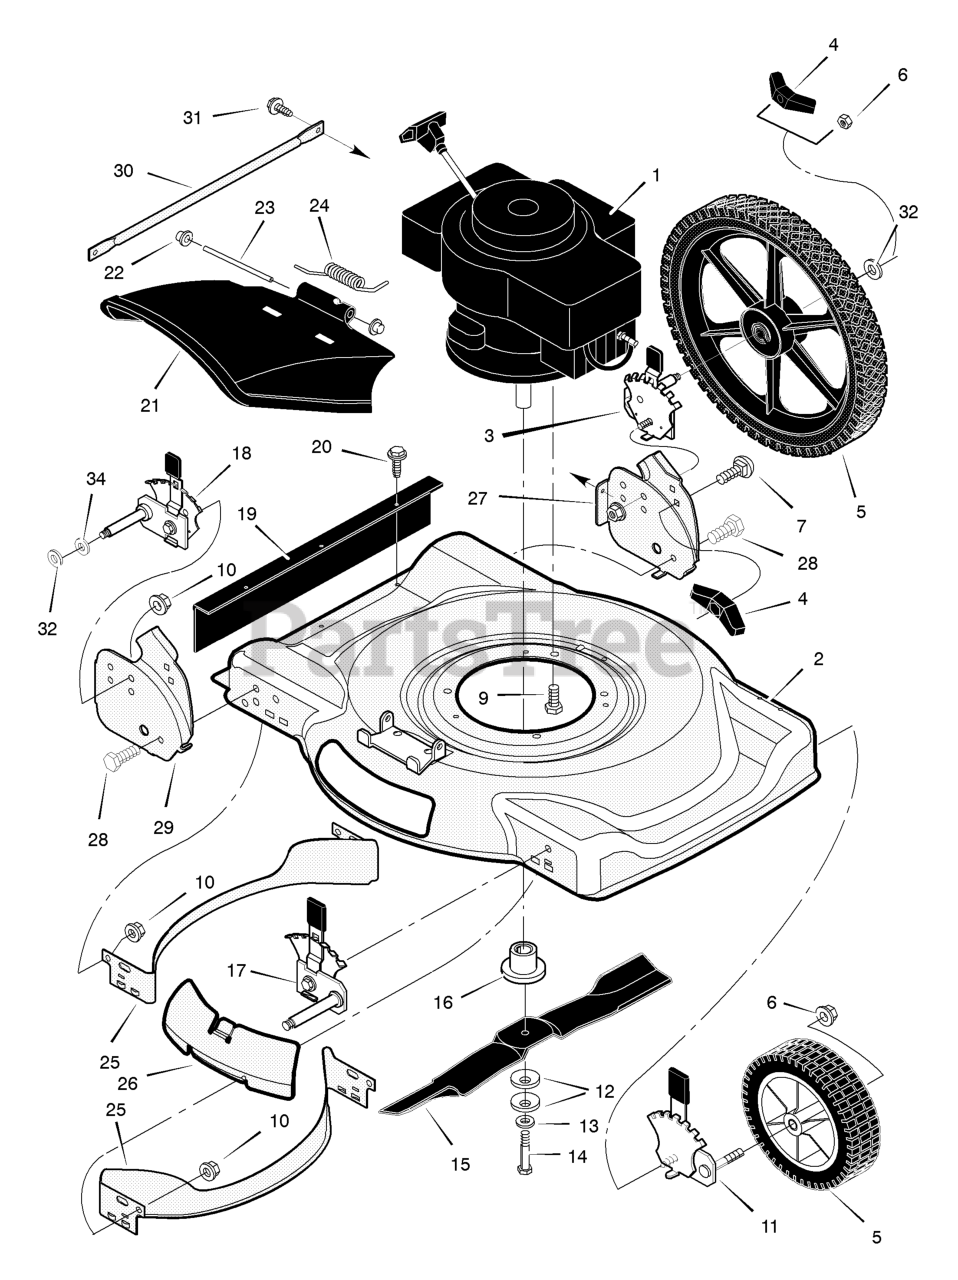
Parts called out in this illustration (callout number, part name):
1	Engine
2	Housing
3	Height Adjuster, Left Rear
5	Wheel and Tire - Front
5	Wheel and Tire - Rear
6	Locknut, Flange
7	Bolt, Carriage
9	Bolt, Engine
10	Nut
11	Height Adjuster, Left Front
12	Washer, Belleville
14	Bolt, Hex
16	Adapter, Blade
17	Height Adjuster, Right Front
18	Height Adjuster, Right Rear
19	Guard, Rear
21	Deflector, Chute
22	Push-On Cap
23	Pin, Pivot
26	Plate, Mulcher
27	Bracket, Left Handle
28	Bolt, Hex
29	Bracket, Right Handle
34	Washer, Spring
